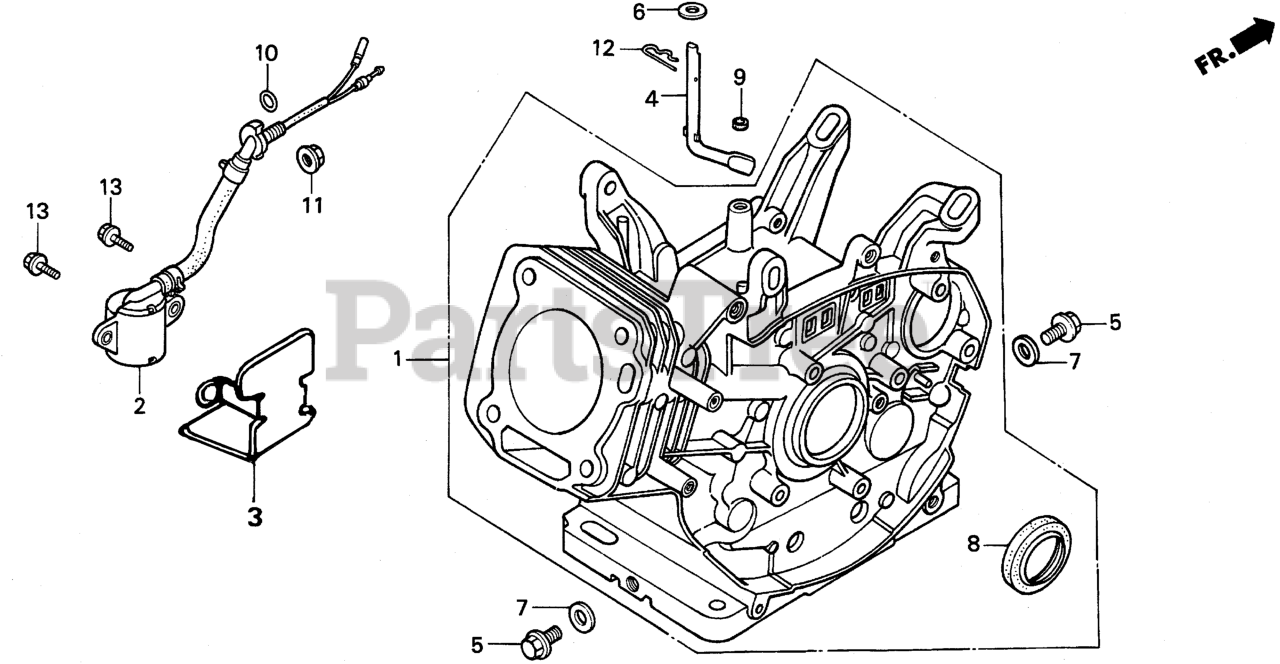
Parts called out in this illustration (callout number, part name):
1	CYLINDER ASSY.
2	SWITCH ASSY., OIL LEVEL
3	PROTECTOR, OIL LEVEL SWITCH
4	SHAFT, GOVERNOR ARM
5	BOLT, DRAIN PLUG
6	WASHER (8.2X17X0.8)
7	WASHER, DRAIN PLUG (12MM)
8	OIL SEAL (30X46X8)
9	OIL SEAL (8X14X5)
10	O-RING (14MM) (ARAI) Use up to Engine SN 2949254.
11	NUT, FLANGE (10MM)
12	PIN, LOCK (8MM)
13	BOLT, FLANGE (6X12) Use up to Engine SN 1543277.
